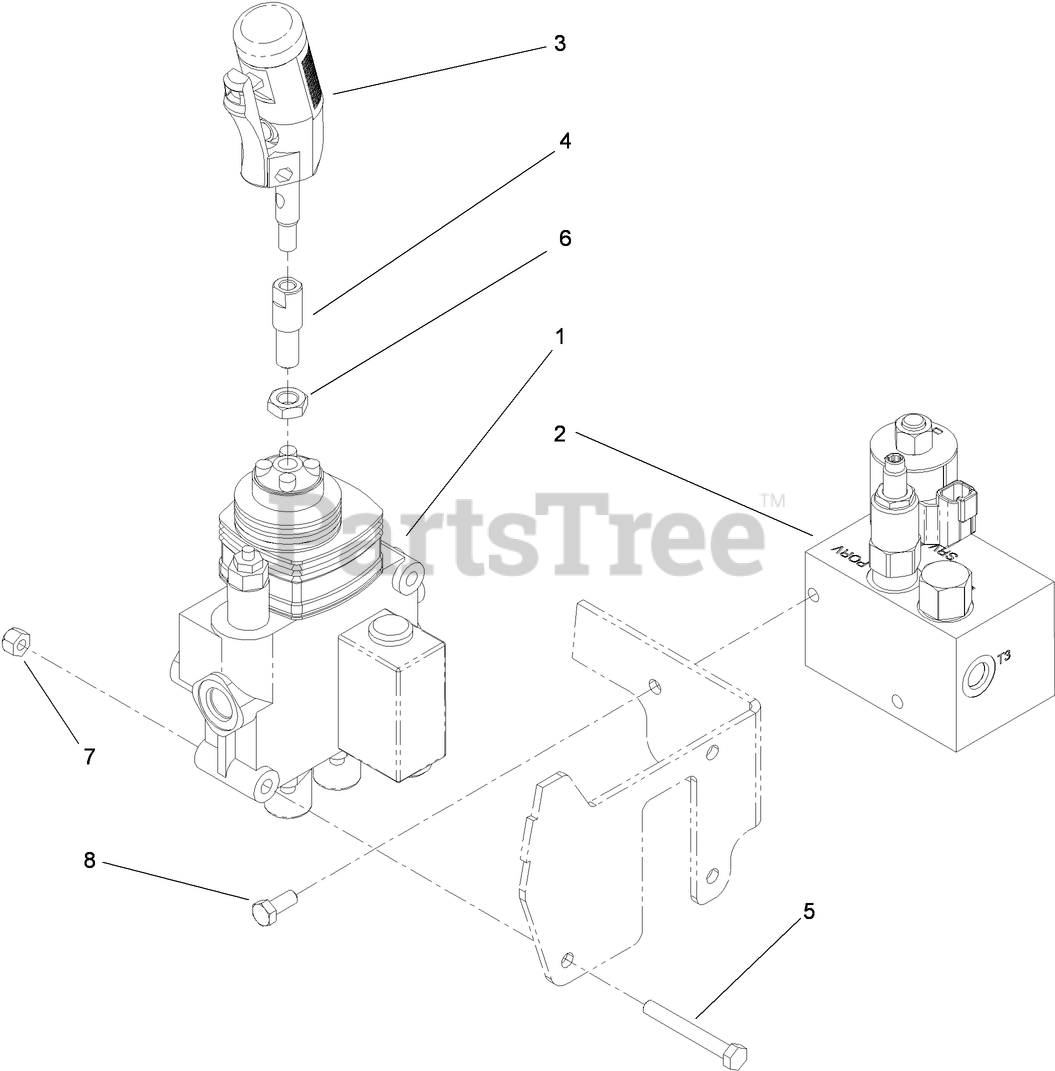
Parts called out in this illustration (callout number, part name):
1	HYD VALVE ASM
2	CUTTER WHEEL VALVE ASM
3	TWO BUTTON HANDLE GRIP ASM
4	ADAPTER-HANDLE
5	SCREW-HH
7	NUT-LOCK, NI
8	SCREW-HH
